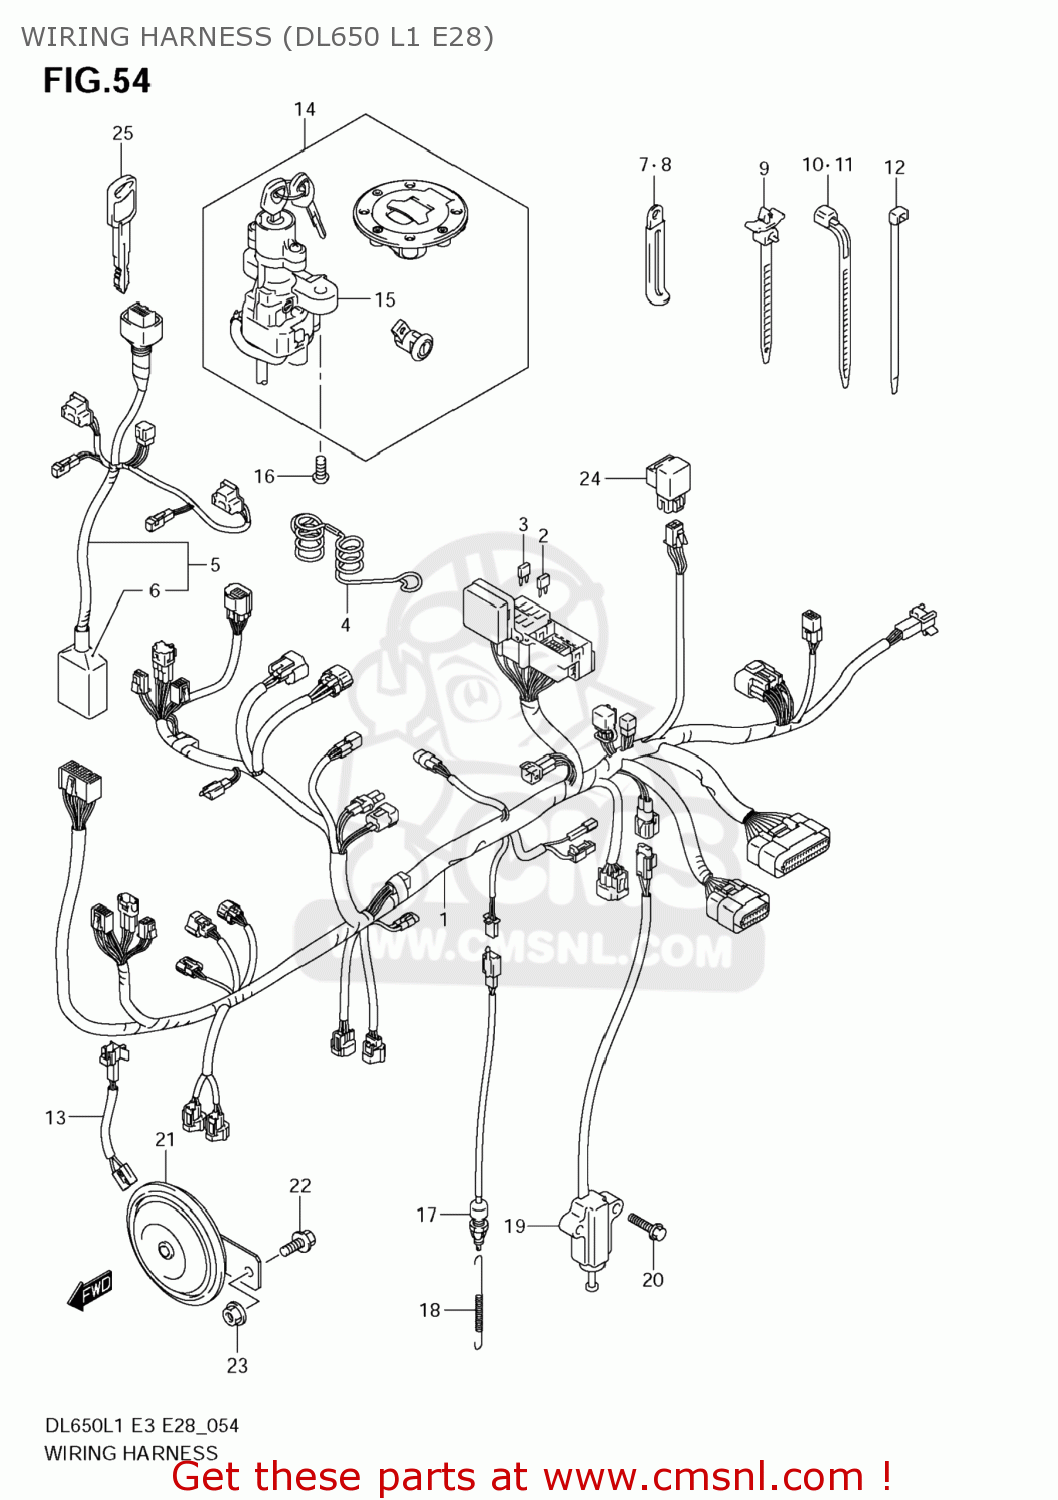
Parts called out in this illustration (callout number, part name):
1	HARNESS,WIRING NO.1
2	FUSE(10A)
3	FUSE(15A)
4	GUIDE,WIRING HARNESS
5	HARNESS,WIRING NO.2
6	COVER,CONNECTOR
7	CLAMP(L:45)
8	CLAMP(L:80)
9	CLAMP(L:120)
10	CLAMP(L:95)
11	CLAMP(L:125)
12	CLAMP(L:145)
13	WIRE,HORN LEAD
14	LOCK SET
15	LOCK ASSY,STEERING
16	BOLT(8X20)
17	SWITCH ASSY,STOP LAMP
18	SPRING
19	SWITCH ASSY,SIDE STAND
20	BOLT
21	HORN ASSY
22	BOLT
23	NUT
24	RELAY ASSY
25	KEY,BLANK
